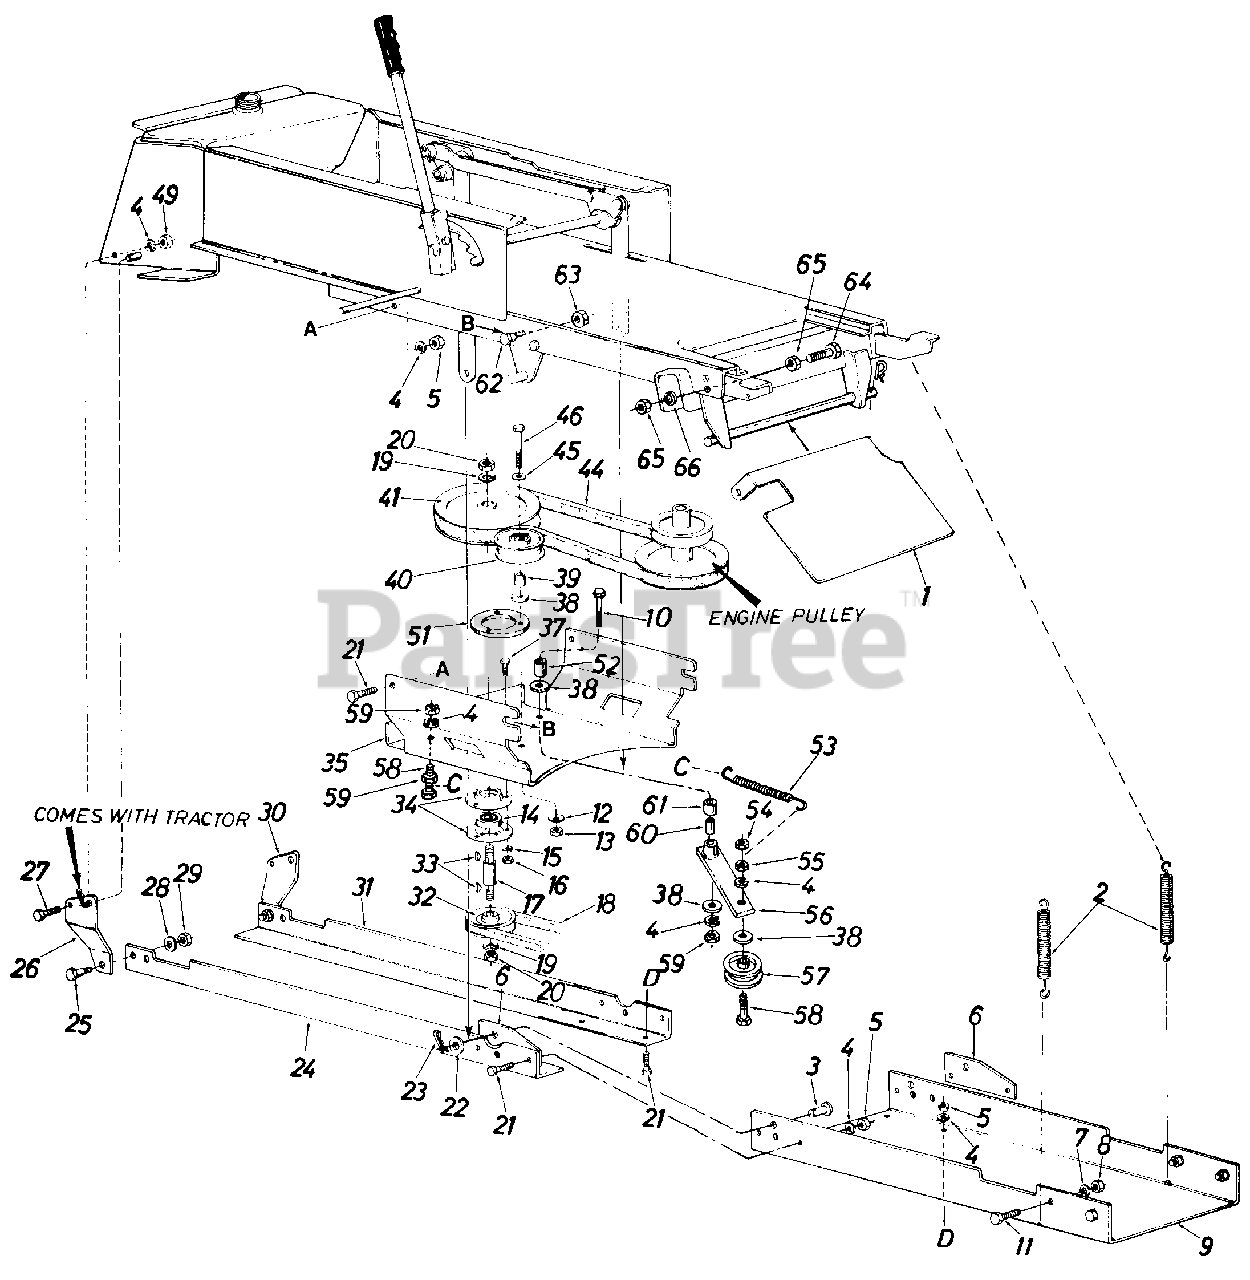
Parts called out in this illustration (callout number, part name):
1	Guide Bracket
2	Helper Spring
3	Clevis Pin
4	L.-Wash. 3/8" I.D.
5	Hex L.-Nut 3/8-24Thd.
6	Attaching Plate
7	L.-Wash. 1/2" I.D.
8	Hex L.-Nut 1/2-20Thd.
9	Front Support Channel
10	Hex Bolt 3/8-16 x 3.75" Lg.
11	Hex Bolt 1/2-20 x 1.25" Lg.
12	Belleville Wash. 3/8" I.D.
13	Hex L.-Nut 3/8-16 Thd.
14	Ball Bearing
15	L.-Wash. 5/16" I.D.
16	Hex Nut 5/16-18 Thd.
17	Spindle
18	"V"-Belt 1/2" x 88" x 2 (Kevlar)
19	L.-Wash. 5/8" I.D.
20	Hex Jam Nut 5/8-11 Thd.
21	Hex Bolt 3/8-24 x 1.00" Lg.
22	Flat Washer
23	Internal Cotter Pin
28	Fl.-Wash. .44" I.D. x 1.38" O.D. x .130
29	Hex L.-Nut 7/16-24 Thd.
30	Rear Hanger Brkt.-L.H.
33	#6 Hi-Pro Key 3/16 x 5/8" Dia.
34	Bearing Housing
35	Supporting Bracket
37	Hex Sems Bolt 5/16-18 x 1.00" Lg.
38	Fl.-Wash. .38" I.D. x 1.00" O.D. x .135
39	Spacer .38" I.D. x .62" O.D.
40	Fl.-Idler Pulley
41	Upper Drive Pulley
44	"V"-Belt 1/2" x 49.8" Lg.
45	Fl.-Wash.
46	Hex Bolt 3/8-16 x 2.50" Lg.
49	Hex Nut 3/8-16 Thd.
53	Extension Spring .54" O.D. x 4.75" Lg.
54	Hex Cent. L.-Nut 3/8-16 Thd.
55	Hex Jam Nut 5/8-11 Thd.
56	Idler Arm Ass'y.
57	Idler Pulley
58	Hex Bolt 3/8-16 x 2.25" Lg.
59	Hex Jam Nut 3/8-16 Thd.
60	Spacer .377" I.D. x .60" O.D. x .830" Lg.
61	Spacer.380" I.D. x .630" O.D. x .565" Lg.
62	Shoulder Bolt .498 Dia. x .340
63	Hex Cent. L.-Nut 3/8-16 Thd.
64	Hex Bolt 1/4-28 x 1.5" Lg.
65	Hex Nut 1/4"-28 Thd.
66	L-Wash 1/4" I.D.
